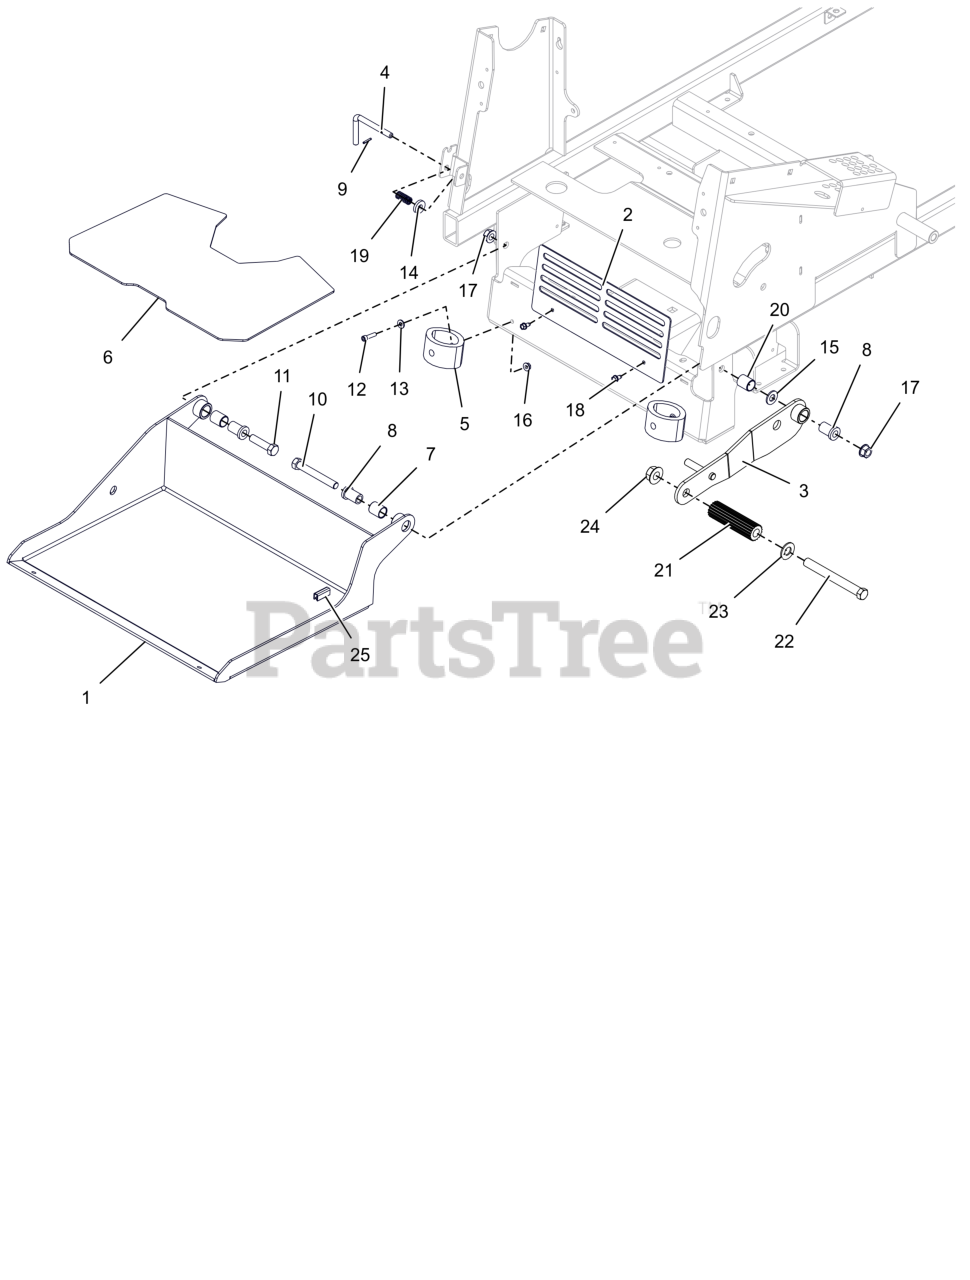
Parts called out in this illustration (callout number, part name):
1	PLATFORM, OPERATOR
2	GUARD, FOOT (RED)
3	BRKT, DECK LIFT FOOT PEDDLE
4	PIN, PLATFORM LOCK
5	BUMPER, PLATFORM
6	TAPE, OPERATOR PLATFORM GRIP
7	BRG, .750 X .875 X 1.000
8	BSHG-FLG .515X.746X1.290X1.000
9	PIN-ROLL .125X.75
10	BLT,HEX .50-13X3.75 G5 ZCC
11	BLT, HEX .50-13X2.00 G5 ZCC
12	SCR, SKH .25-20X1.00
13	WSHR,FLT .281X.625X.065 ZCC
14	WSHR, FLT .406X1.00X.188 ZCC
15	WSHR,FLT .531X1.062X.095 ZCC
16	NUT-LK-CTR-FLG .25-20 ZC120
17	NUT-LK-CTR-FLG .500-13 GG ZCC
18	SCR-TAP .25-20X.50 HWH ZCC
19	SPRING, COMPRESSION
20	BRG, .750 X .875 X 1.000
21	ROD, FOOT PEDAL (BLACK)
22	BLT, HEX .62-11X5.50 G5 FBP
23	WSHRFLT 5/8SAE CARBHARD FBP
24	NUT,FLG-TOP LK .625-11 FBP
25	STRIP, COWL
